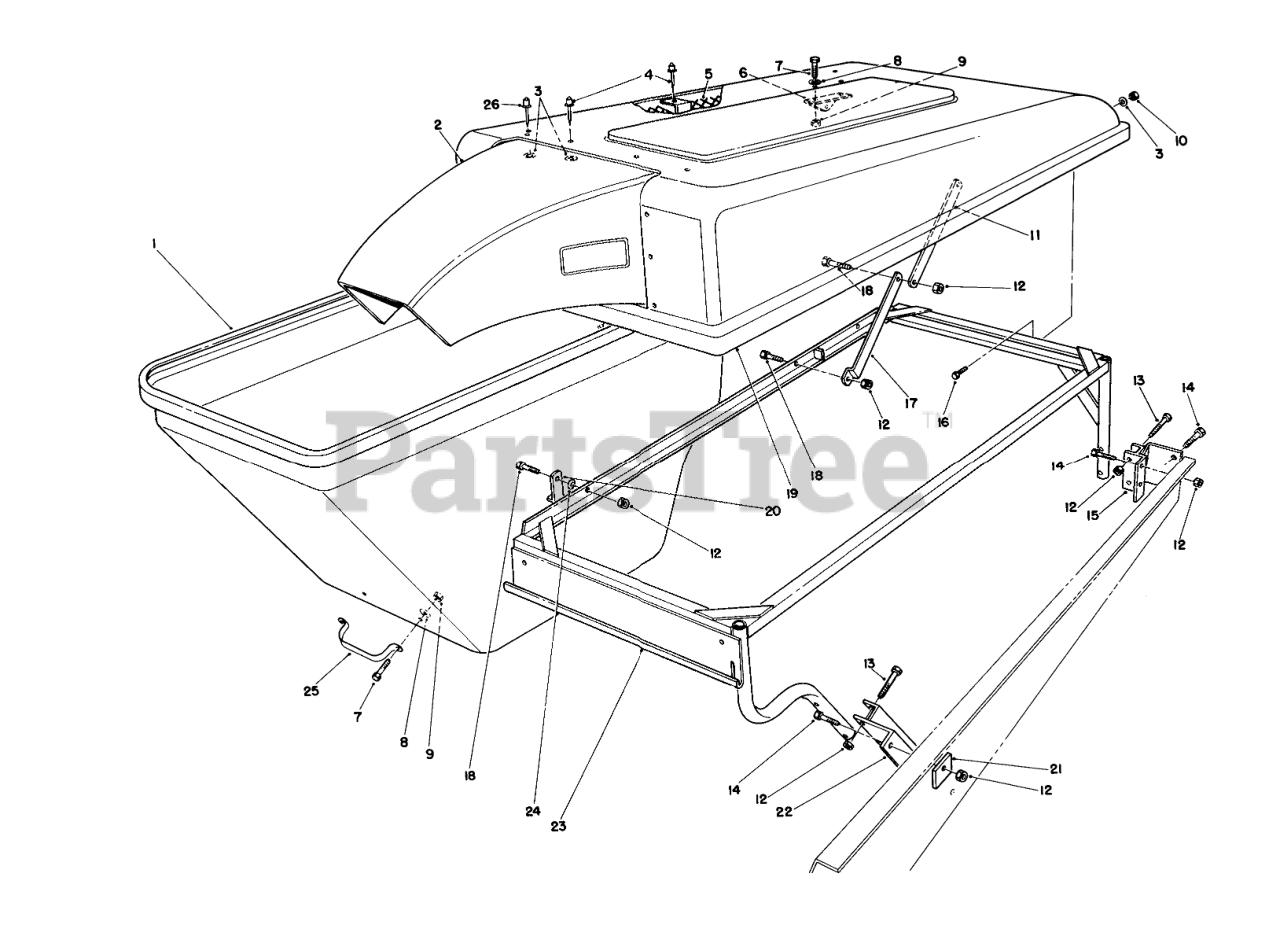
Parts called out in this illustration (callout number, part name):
1	BAGGER HOPPER
2	BAGGER SNOUT
3	WASHER-FLAT
5	Bagger Screen
6	Pivot
7	SCREW-HH
8	WASHER-FLAT
9	NUT-LOCK, NI
10	NUT-LOCK, NI
11	Link
12	NUT-LOCK, NI
13	SCREW-HH
14	SCREW-HH
15	Bracket-Rear
17	Link-Bag
18	SCREW-HH
19	Hood-Bagger
20	Latch-Hopper
21	Plate-Reinforcing
22	Bracket-Front
23	HOPPER FRAME WA
24	WASHER-SPRING
25	Handle
26	RIVET-POP
